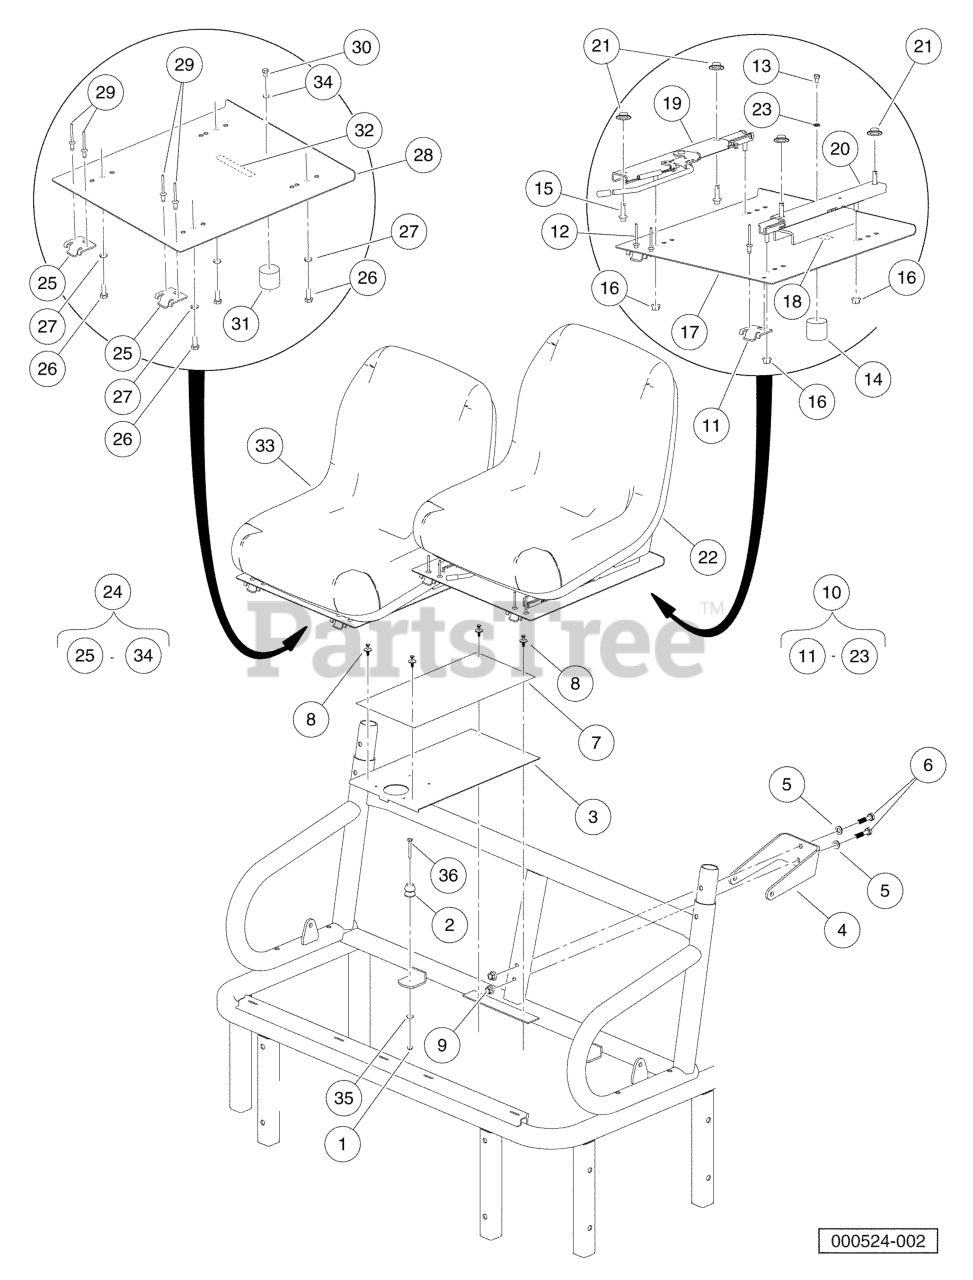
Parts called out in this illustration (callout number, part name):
1	LOCKNUT, M6-1.00 NYLON INSERT
2	SEAT HOLDER BASE
3	PAN, CENTER, CLOSEOUT
4	BRKT, SEATBELT, BOLT-ON
5	WASHER, HARD, M10, ZN-NI/BLK
6	BOLT, M10 X 45, ZN-NI/BLK
7	COVER, CENTER CONSOLE
8	SCREW, TUFLOK PANEL, 1/4
9	NUT, FLANGED, M10 X 1.5, BLACK
10	Asm, Bracket Seat, Adj, Blk
11	HINGE PLATE
12	RIVET, 1/4 X .438 BLIND
13	SCREW, 6M-1.00 X 10MM HEX HEAD
14	SEAT HOLDER CUP
15	BOLT - FLANGED HD, M8 X 30.0
16	NUT FLG, M8 X 1.25 MECH DEF
17	PAN, SEAT, DRIVER ASM
18	DECAL, WARNING HOT SURFACE
19	ADJUSTER, FORE/AFT
20	ADJUSTER, SLIDER
21	WASHER, BELL
22	SEAT, BUCKET, BLACK
23	LOCKWASHER, 1/4 HELICAL SPLIT
24	Asm, Bracket Seat, Passenger, Blk
25	HINGE PLATE
26	SCREW, M8-125 X 22 HEX GR.8.8
28	PAN, SEAT - PASSENGER
29	RIVET, 1/4 X .438 BLIND
30	SCREW, 6M-1.00 X 10MM HEX HEAD
31	SEAT HOLDER CUP
32	DECAL, WARNING HOT SURFACE
33	SEAT, BUCKET, BLACK
34	LOCKWASHER, 1/4 HELICAL SPLIT
35	WASHER 1/4 FLAT
36	BOLT, M6 X 1 X 45
